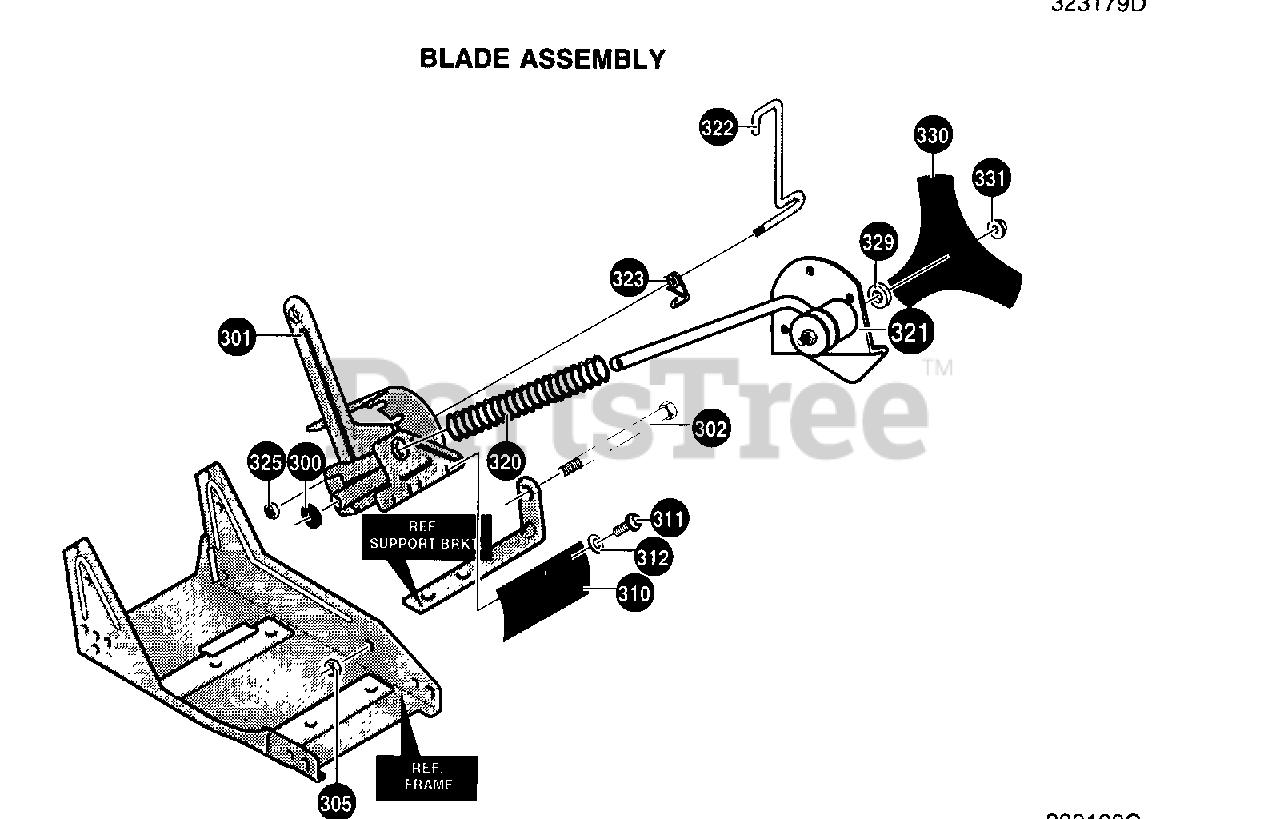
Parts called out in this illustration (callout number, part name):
300	Flatwasher, .531 x 1.06 x .095
301	Quill Suppt. Assy.
302	Shoulder Bolt 3/8-16
305	Nut, 3/8-16 Reghexctrlk
310	Deflector, Rubber
311	Screw, 10-16 x .50 Tap
312	Flatwasher, .203 x .56 x .040
320	Compression Spring
321	Quill Assembly, Lrg Suppt
322	Index Lever
323	Torsion Spring
325	Nut, 5/16-18 Reghexctrlk
329	Flatwasher, .515 x 1.38 x .119
330	Blade Edger
331	Nut, 1/-20 Wdfl
